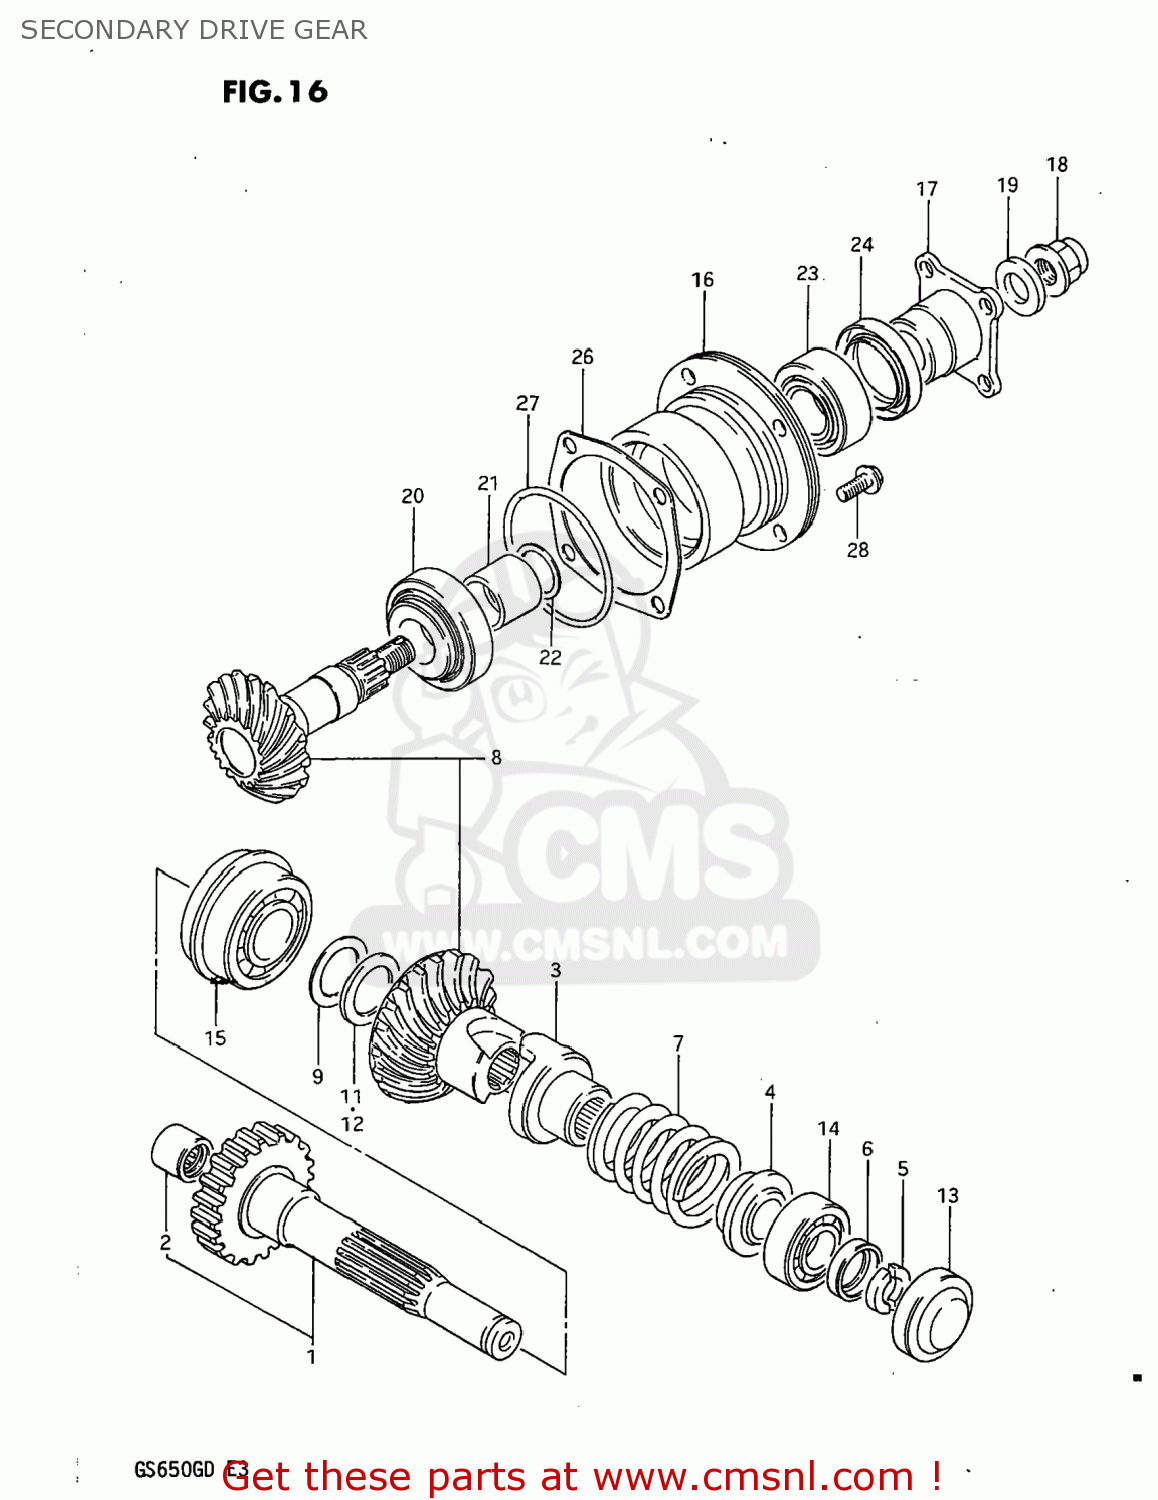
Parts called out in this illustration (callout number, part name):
1	SHAFT,OUTPUT
2	BEARING(15X23X20)
3	DOG
4	STOPPER
5	STOPPER,CAM DOG
6	HOLDER,CAM DOG STOPPER
7	SPRING
8	SECONDARY GEAR SET
9	SHIM,SECONDARY DRIVE
10	SHIM SET,SECONDARY DRIVE BEVEL
11	SHIM,SECONDARY DRIVE BEVEL
12	SHIM,SECONDARY DRIVE BEVEL
13	PLUG
14	BEARING(20X47X14)
15	BALL BEARING 30X62X24
16	HOUSING,SECONDARY DRIVE
17	FLANGE,UNIVERSAL JOINT
18	NUT
19	WASHER(14X29X4)
20	TAPER,ROLLER BEARING
21	SPACER (25.2X30X40)
22	SHIM (25X30X2
23	BEARING
24	SEAL,OIL(35X52X9)
25	SHIM SET,SECONDARY DRIVE
26	SHIM,DRIVEN GEAR HOUSING
27	O RING(D:3.1,ID:69.4)
28	BOLT
